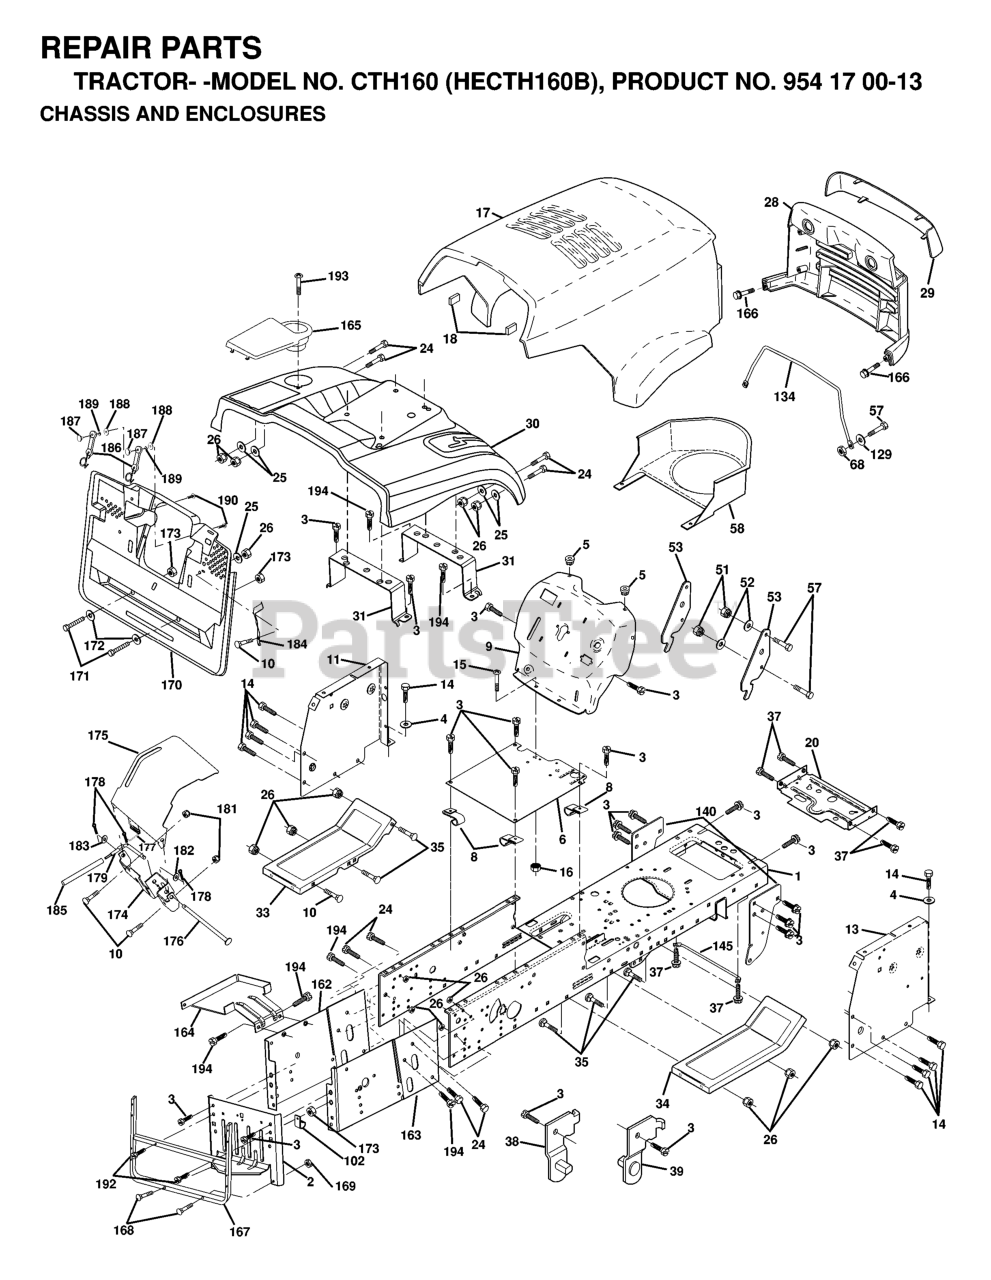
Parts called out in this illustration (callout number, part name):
3	SCREW
4	Washer 13/32 X 3/4 X 16 Ga.
5	BUMPER.RUBBER.HOOD
6	SADDLE FLAT
8	CLIP,INSULATOR
10	BOLT D
11	PANEL DASH LH
13	DASH PANEL
15	Screw, Machine, Truss Head 5/16-18 UNC x 3/4
16	NUT
17	HOOD
18	BUMPER HOOD T
20	PLATE MTG
25	WASHER
26	NUT
28	GRILL
29	LENS
30	FENDER
31	BRACKET SUPPORT FENDER
33	FOOT REST LH
34	FOOTREST RH
37	Screw 5/16-18 x 1/2 Hex, Self Tapping 5/16-18 x 1/2
38	BRACKET LH PIVOT
39	BRACKET RH PIVOT
51	LOCKNUT.NYLOC.1/4-20
53	BRACKET PNT PICK OFF LT/PL
57	BOLT
58	AIR CONDUCTOR
68	NUT
102	CLIP T
134	ROD SUPPORT HOOD LT/PL HUS.
140	BRACKET SUSPENSION FRONT
145	ROD PIVOT CHASSIS/HOOD
165	COVER BATTERY
166	SCREW
167	SUPPORT.ASM.BACKPLATE
168	BOLT.ROUND.HEAD.SQUARE.NECK
169	NUT T
170	COVER BACKPLATE
171	Bolt Hex 3/8-16 x 2-1/2 Gr. 5
172	WASHER
176	HINGE PIN
177	SPRING COVER LH
178	COTTER PIN
180	BOLT RB
181	LOCKNUT
183	WASHER
185	TUBE LEVER
186	LATCH ASSY
187	WELDNUT
189	LOCKWASHER #10
190	SCREW
192	SCREW LT
193	SCREW LT
194	SCREW 3/8-16X3/4
